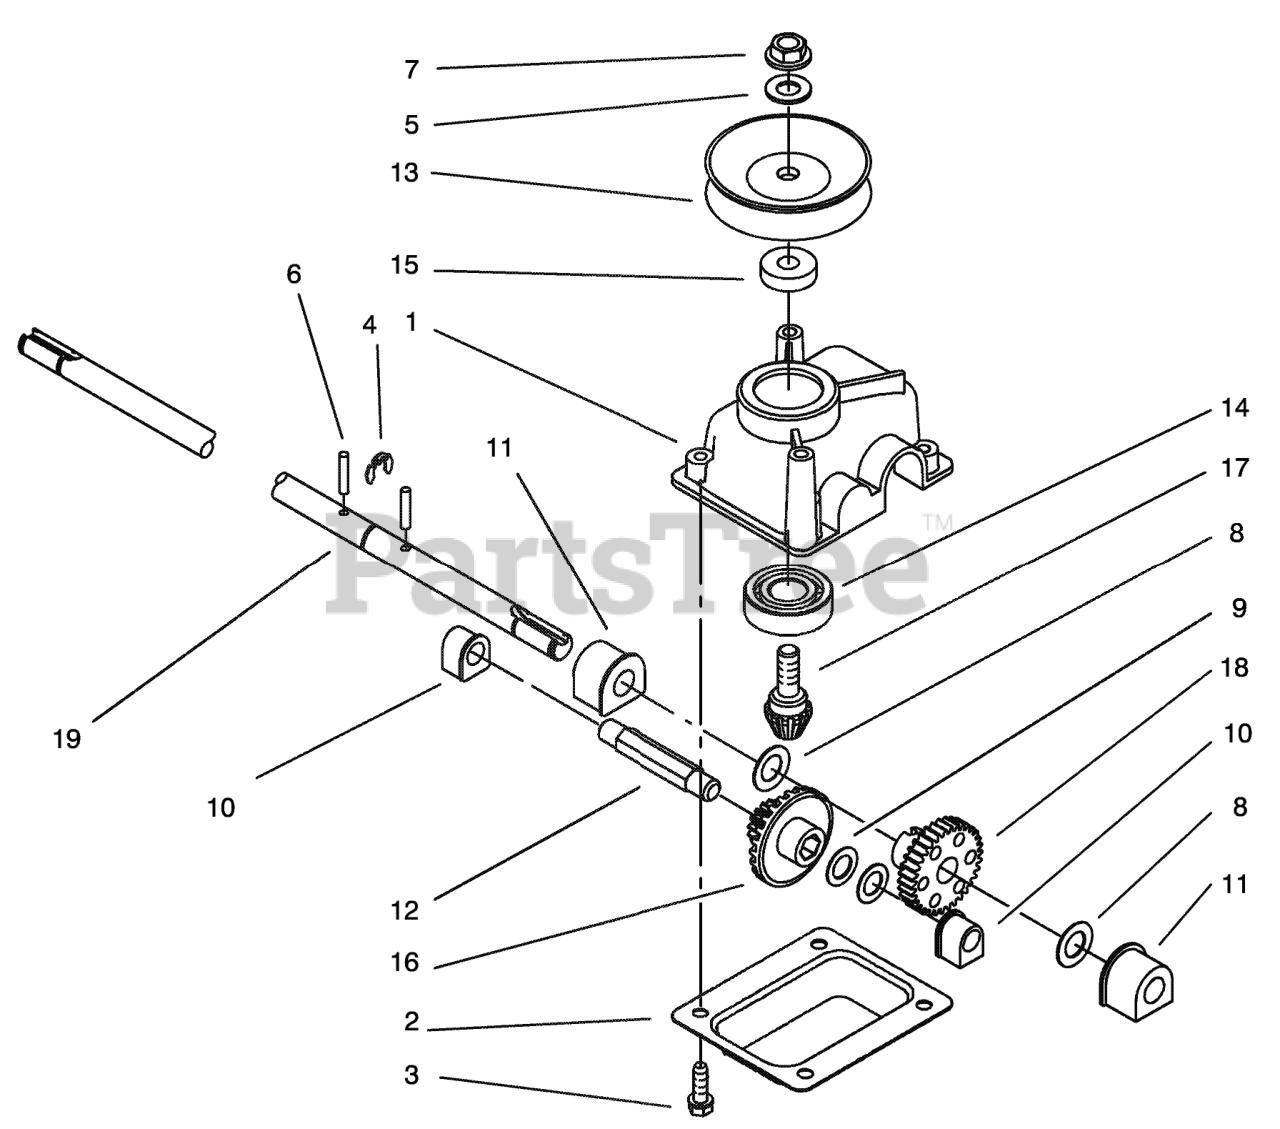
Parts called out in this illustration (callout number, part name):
1	CASE-GEAR
2	COVER-CASE, GEAR
3	SCREW-HWH
4	RING-RETAINING
5	WASHER-FLAT
6	PIN-GROOVE
7	NUT-HEX
8	WASHER-PLAIN
9	WASHER-THRUST
10	BUSHING
11	BUSHING
12	SHAFT-INTERMEDIATE
13	PULLEY-HALF
14	BEARING-BALL
15	SPACER
16	GEAR-15T SPUR, 37T BEVEL
17	GEAR-PINION, BEVEL
19	SHAFT-OUTPUT
